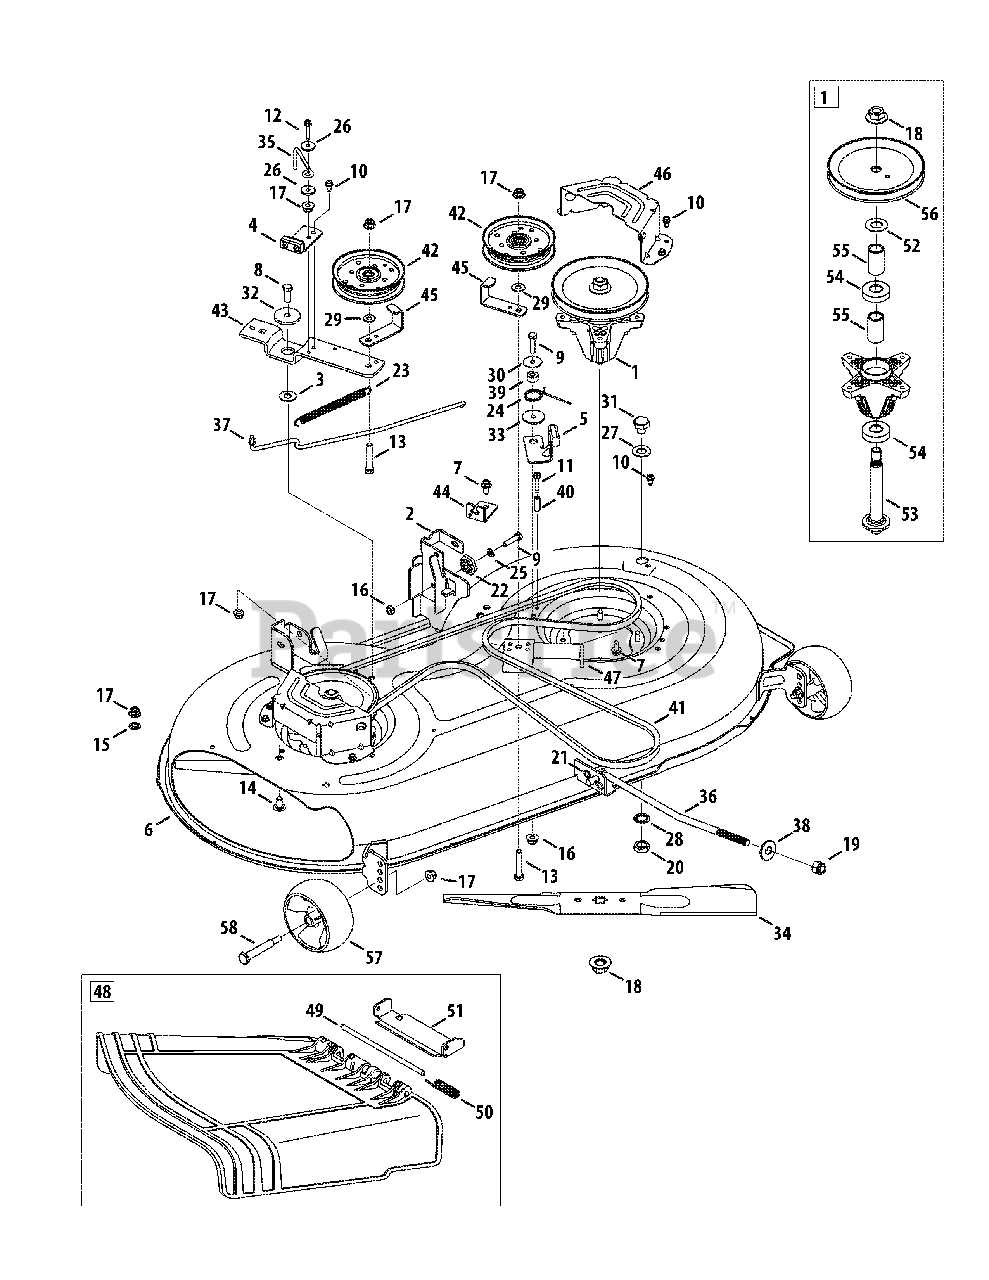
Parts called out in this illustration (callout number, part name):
1	Spindle Pulley Assembly
2	Deck Hanger Bracket Assembly
3	Wash, Flat, .385 x 1.0 x .030
4	Brake Assembly
5	Brake Assembly
6	Deck
7	Screw, 5/16-18 x .750
8	Screw, 3/8-16 x 1.00
9	Hex Screw, 5/16-18 x 1.25
10	Screw, 1/4-20 x .500
11	Screw, 1/4-20 x 1.50
12	Screw, 1/4-20 x 1.250
13	Hex Head Screw, 3/8-16
14	Carriage Bolt, 3/8-16 x .75
15	Push Nut, 3/8
16	Flangelock Nut, 5/16-18
17	Flangelock Nut, 3/8-16
18	Flange Nut, 5/8-18
19	Flangelock Nut, 1/2-13
20	Hex Nut, M16 - 1.5
21	Cotter Pin, Bow-Tie
22	Deck Adjuster Gear
23	Extension Spring, .62 x 6.12
24	Torsion Spring, 1.0 x 1.17
25	Lock Washer, 5/16
26	Flat Washer, .265 x 9.38 x .120
27	Flat Washer, .64 x 1.24 x .06
28	Flat Washer, .5/8 Int. Tth.
29	Flat Washer, .385 x .870 x .092
30	Flat Washer, .330 x 1.25 x .06
31	Bolt Plug, M16 x 1.5
32	Shoulder Spacer, .8840 x .190
33	Shoulder Spacer, .5000 x .1475
34	Cutting Blade, 21.23": 2 in 1
35	Belt Keeper Rod
36	Deck Lift Rod
37	Brake Control Rod
38	Deck Lift Pivot Cup
39	Spacer
40	Spacer
41	V-Type Belt, 96.5
42	Idler Pulley, 4.25 Diameter
43	Idler Pivot Bracket
44	Deck Cable Engagement Bracket
45	Belt Pulley Guard
46	Deck Belt Cover
47	Deck Support Bracket
48	Chute Deflector Assembly
49	Hinge Pin
50	Torsion Spring, .44 x 2.0
51	Chute Bracket
52	Flat Washer, .760 x 1.50
53	Spindle Shaft
54	Ball Bearing, .787 x 1.85 x .551
55	Spacer, .792 x 1.060 x 1.860
56	Spindle Pulley
57	Deck Wheel, 5" Dia. Ball
58	Shoulder Bolt, 3/8-16
